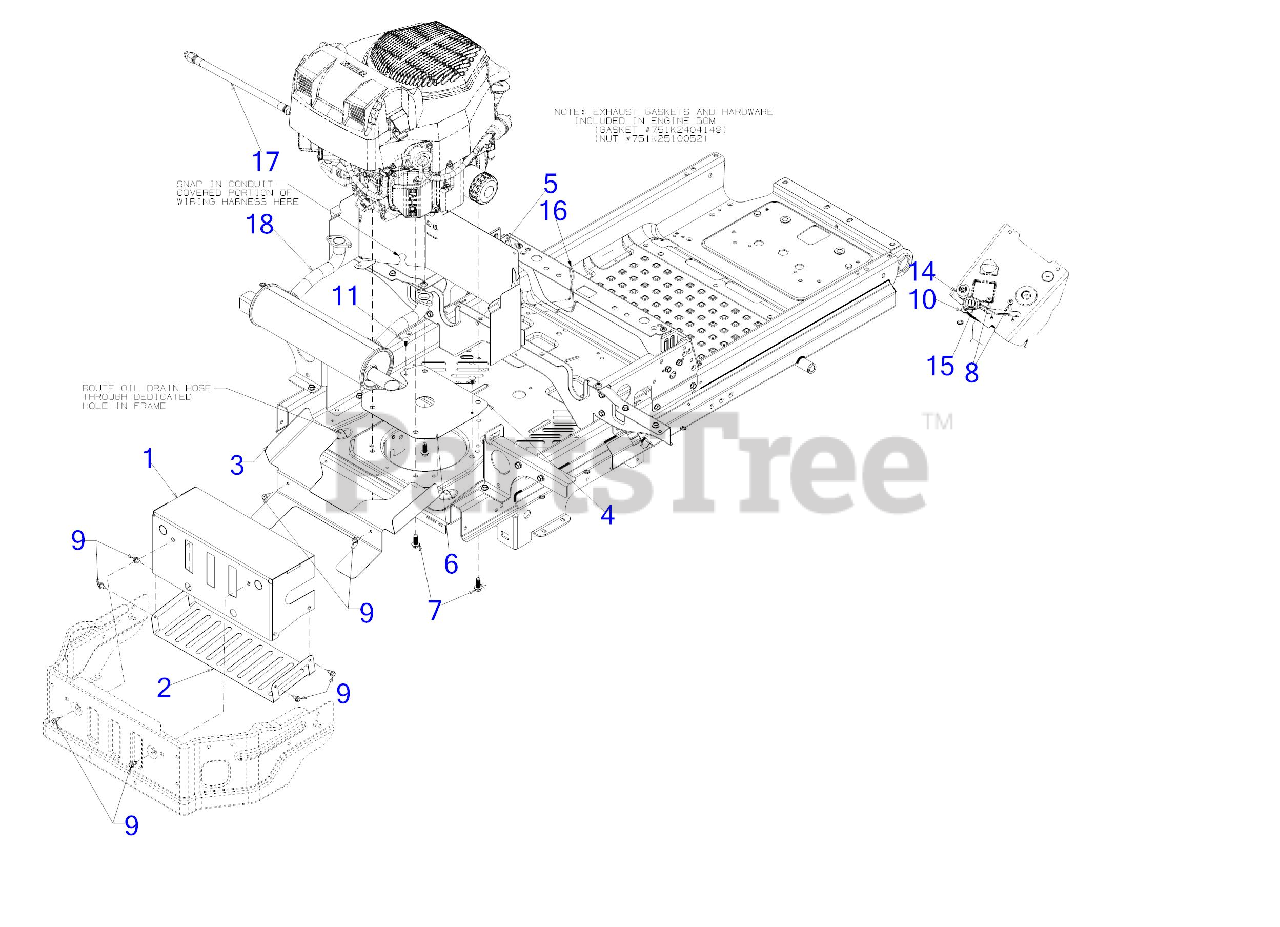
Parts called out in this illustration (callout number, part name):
1	MUFFLER SHIELD BRACKET
2	LOWER MUFFLER BRACKET
3	MUFFLER BRACKET
4	ENGINE SHIELD PLATE
5	ENGINE SHIELD BRACKET
6	SCREW 5/16-18 x .750
7	SCREW 3/8-16 x 1
8	SCREW 1/4-20 x .5
9	SCREW 1/4-20X.625
10	HEX FLANGE NUT
11	RATCHET CLIP .250
14	61" CHOKE CABLE
15	THROTTLE CABLE 59"
16	TANK SUPPORT ROD
17	OIL DRAIN HOSE
18	ROUND MUFFLER
